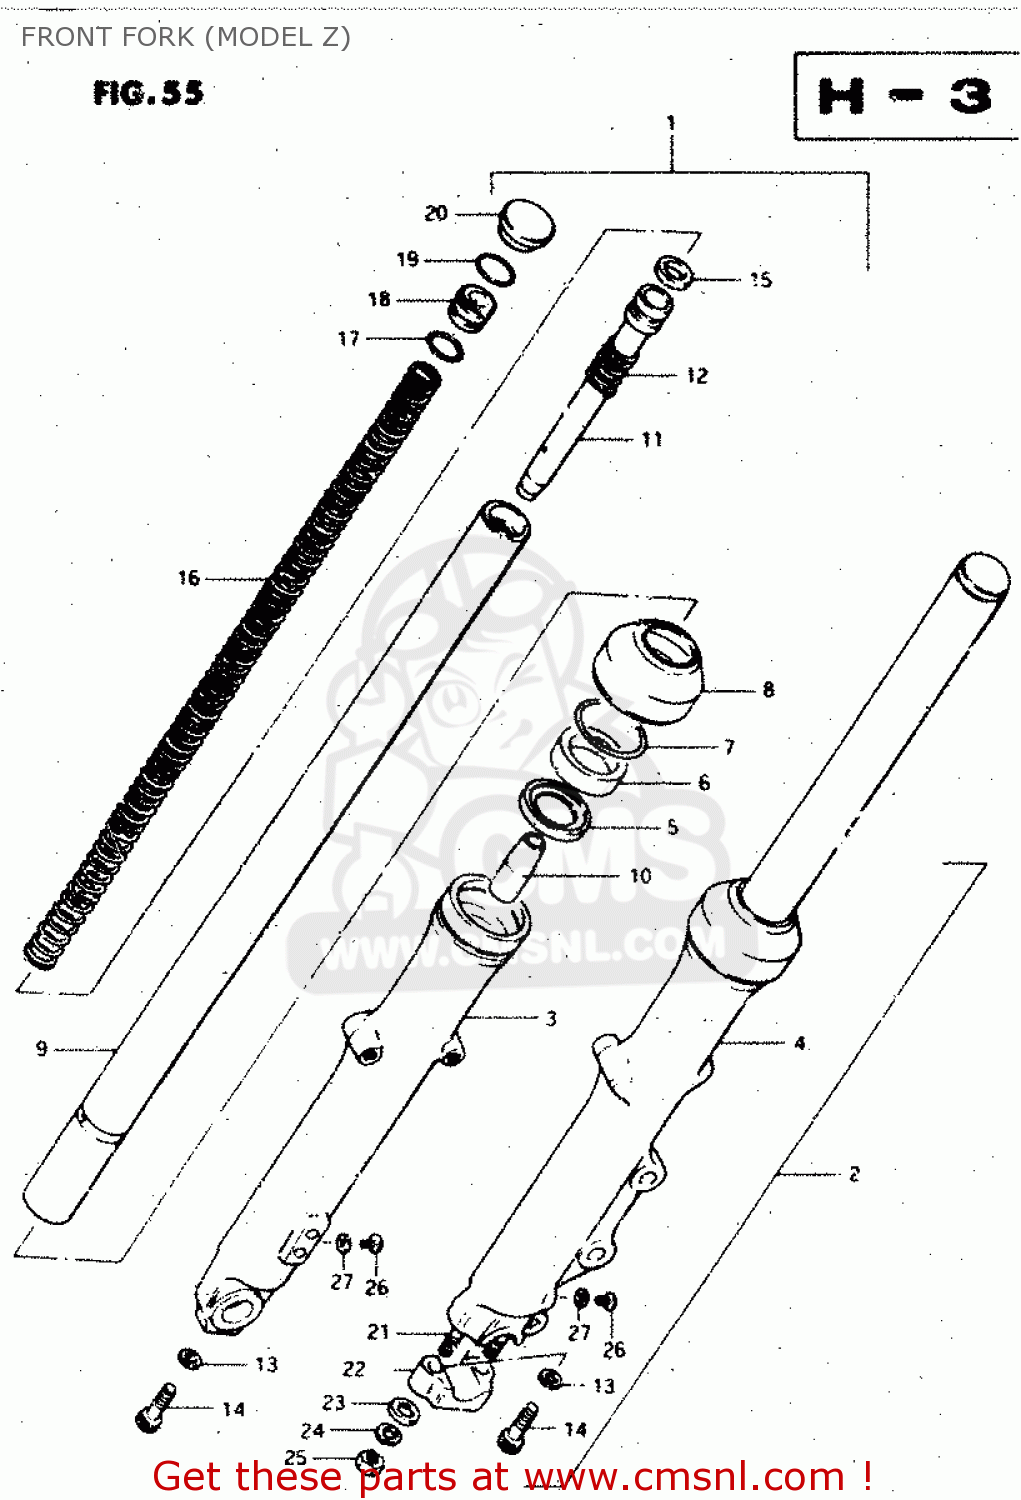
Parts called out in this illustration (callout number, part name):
1	DAMPER ASSEMBLY,RIGHT
2	DUMPER ASSY, LH
3	OUTER TUBE, RH
4	OUTER TUBE, LH
5	SPACER,OIL SEAL
6	OIL SEAL,FRONT FORK
7	CIRCLIP,FORK OIL SEAL
8	DUST SEAL
9	TUBE,FORK,INNER
10	PIECE,OIL LOCK
11	CYLINDER,FRONT FORK
12	SPRING,REBOUND
13	GASKET (NAS)
14	BOLT(8X27)
15	RING,PISTON
16	SPRING
17	O RING
18	SEAT,SPRING
19	RING,STOPPER
20	CAP,FRONT FORK
21	STUD 8X25
22	HOLDER,AXLE
23	WASHER
24	LOCK WASHER
25	NUT (8MM)
26	SCREW 4X6
27	GASKET (NAS)
